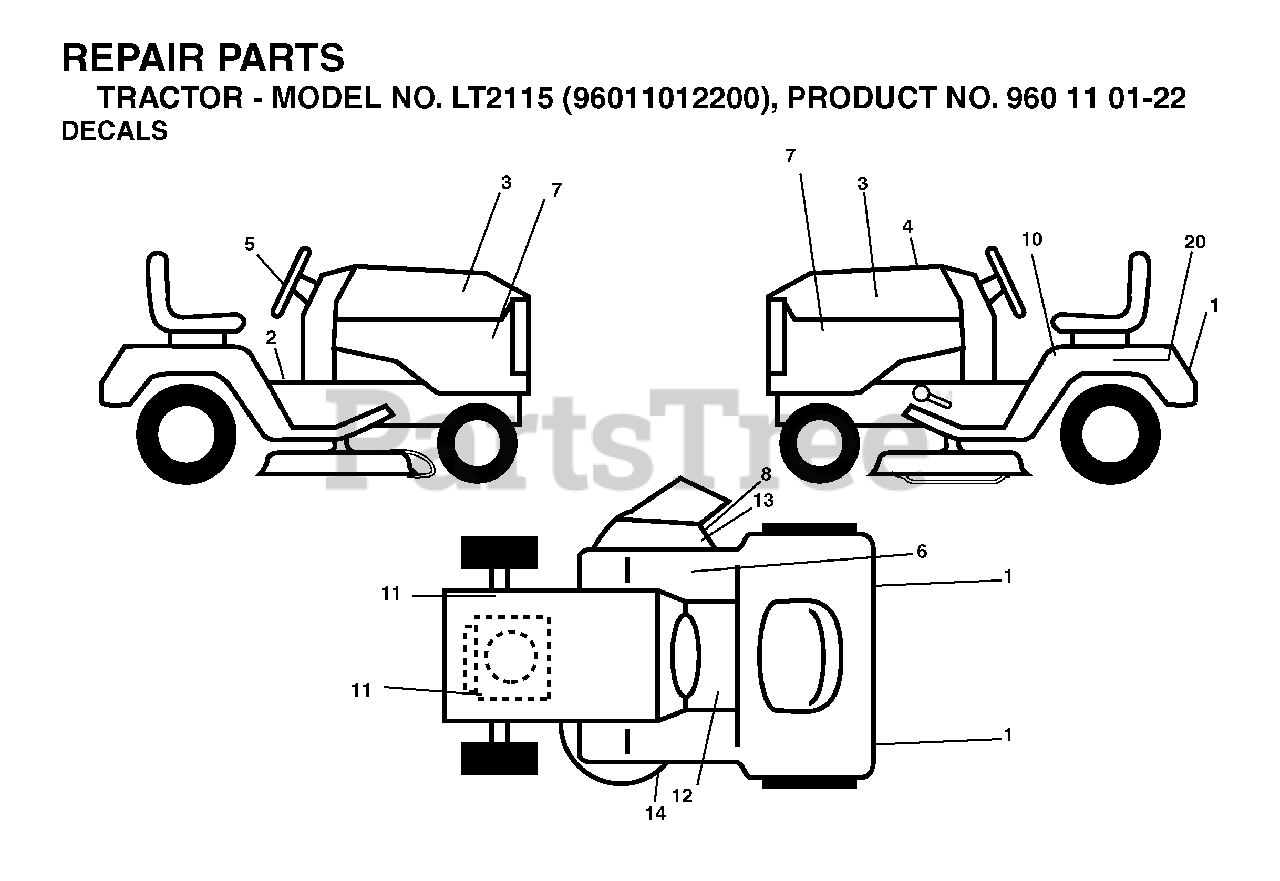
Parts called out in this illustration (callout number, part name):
2	DECAL PARK BRAKE
8	DECAL.INTERNATIONL.CUTFINGER
10	DECAL READ OWNER'S MAN SYMS
13	DECAL, DEFLECT WARNING
14	DECAL.V-BELT.SCHEMATIC.36/38/9
20	DECAL BTRY SYMBOLS
